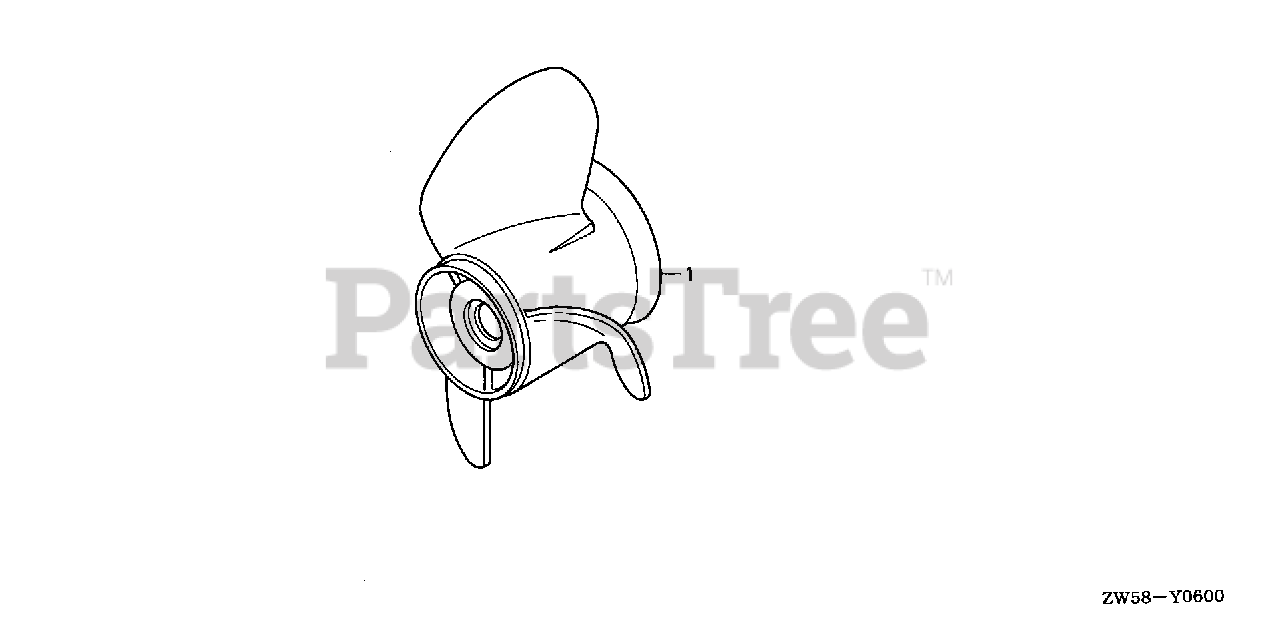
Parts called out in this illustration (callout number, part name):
1	PROPELLER, THREE-BLADE (13-1/4X19) (SUS/HAC)
1	PROPELLER, THREE-BLADE (13-1/4X21) (SUS/HAC)
1	PROPELLER, THREE-BLADE (13-1/4X15) (SUS/HAC)
1	PROPELLER, THREE-BLADE (13-1/4X17) (SUS/HAC)
1	PROPELLER, THREE-BLADE (13X19) (SUS)
1	PROPELLER, THREE-BLADE (13X21) (SUS)
1	PROPELLER, THREE-BLADE (14X11) *NH283* (AL) (STIN GRAY)
1	PROPELLER, THREE-BLADE (13-3/4X13) *NH283* (AL) (STIN GRAY)
1	PROPELLER, THREE-BLADE (13-1/4X17) *NH283* (AL) (STIN GRAY)
1	PROPELLER, THREE-BLADE (13X21) *NH283* (AL) (STIN GRAY)
1	PROPELLER, THREE-BLADE (13X19) *NH283* (AL) (STIN GRAY)
1	PROPELLER, THREE-BLADE (13-1/4X17) (SUS)
1	PROPELLER, THREE-BLADE (13-1/2X15) (AL)
